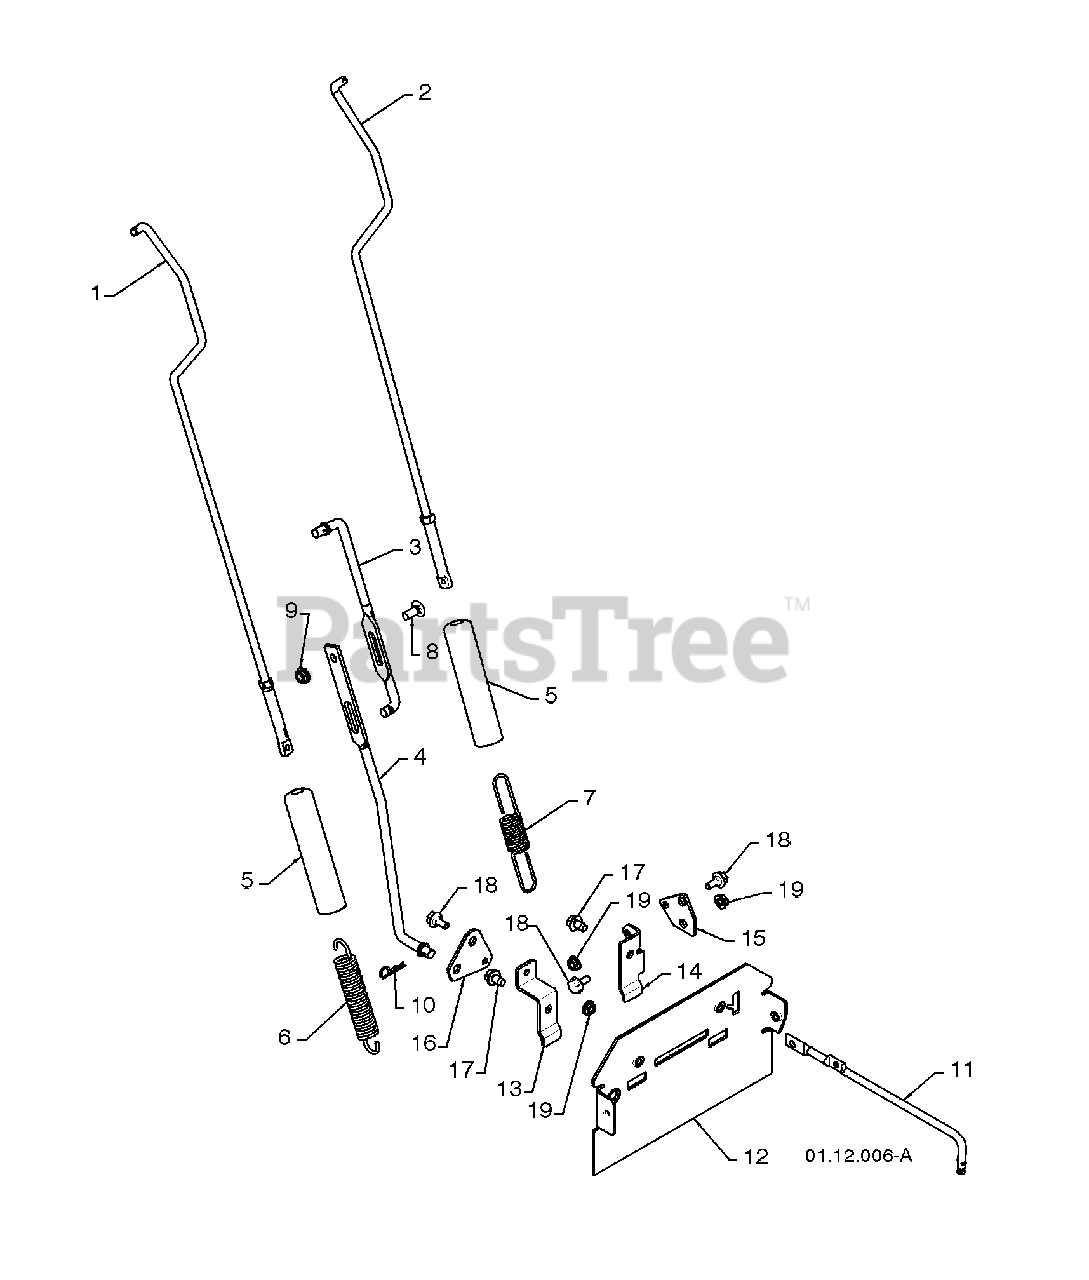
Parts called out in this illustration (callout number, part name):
1	IMPELLER ROD ASSEMBLY
2	TRACTION ROD ASSEMBLY
3	SHIFTER ROD TOP
4	SHIFTER ROD BOTTOM
5	SPRING SLEEVE
6	IMPELLER SPRING
7	TRACTION SPRING
8	CARRIAGE BOLT 5/16-18 X .750
9	NUT 5/16-18
11	CLUTCH ROD
12	REAR PLATE
13	SHIFTER PLATE BRACKET
14	CLUTCH PLATE BRACKET
15	CLUTCH PLATE
16	SHIFTER PLATE
17	BOLT 5/16-18 X .500
18	SHOULDER BOLT 1/4-20 X .500
19	NUT 1/4-20
